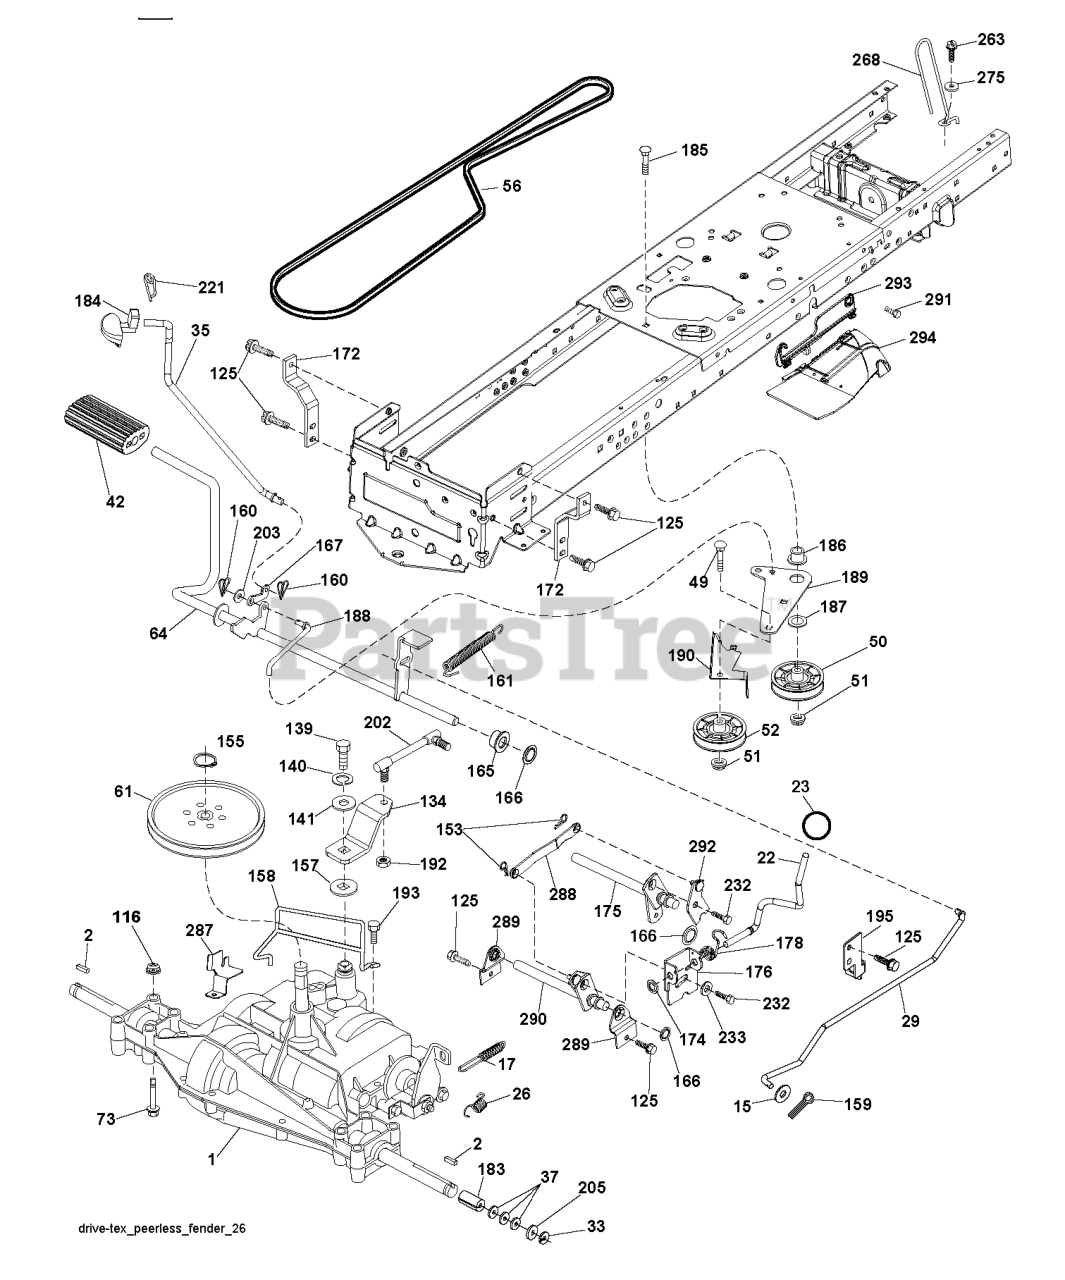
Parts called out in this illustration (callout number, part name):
2	SQUARE KEY
15	WASHER
17	SPRING.BRAKE.PEERLESS.TEX
22	SHIFTER.ASM.HANDLE.SRD
23	KNOB.DUCKHEAD.1/2
26	SPRING.BRAKE.RTN.GR.DR
29	ROD.BRAKE.PEERLESS
35	ROD.CNTRL.PARK.PREDATOR.LT.TEX
42	PEDAL COVER T
50	IDLER.FLAT.910.OFFSET
51	NUT LOCK FLG 3/8-16 UNC
52	IDLER.V-GROOVE.910.OFFSET
56	BELT, V GROUND DRIVE 95 25
61	PULLEY
64	SHAFT.ASM.PEDAL.BRAKE.
73	BOLT HEX 5/16-18 GR 5
116	NUT LOCK HEX FLANGE 5/16-18
125	SCREW
139	BOLT 1/4-28X3/4
140	LOCKWASHER
153	RETAINER M
155	RETAINING RING LT
157	WASH-SHFT PLT LT
158	KEEPER.PMS.18/20.D4365
159	COTTER PIN
160	RETAINER CLIP
161	SPRING, RETURN LT
165	BUSHING.SHAFT.BRAKE.HAND
166	NUT.PUSH.625.2006
167	LATCH.BRAKE.SPRING
172	STRAP.TRQ.LH.GEAR.DRIV
174	NUT.PUSH.500.2006
175	SHAFT ASM SHIFT
176	ARM.CLEVIS.ROD.SHIFT
178	SPRING.TORSION.LIFT.HANDLE
183	SPACER AXLE
184	HANDLE PARKING BRAKE
186	SPACER.RETAINER
187	WASHER 12/32X2X10GA
188	RP.LINK.CLUTCH.GROUND.DRIVE
189	BELLCRANK.GROUND.DRIVE.TEX.
190	KEEPER.BELLCRANK.DRIVE
192	NUT LOCK CENTER 1/4 -28 FNTHD
193	SCREW 5/16"
195	BRKT.ROD.BRAKE.PEERLES
202	LINK.SHIFT.PMST.18" (SPG1286)
203	WASHER
221	RETAINER.SPRING.CLIP.H
232	BOLT FIN HEX 7/16-14 X 1
233	WASHER SERRATED
263	SCREW, 3/8-16X3/4
268	WASHER
275	GUARD MUFFLER
287	KEEPER.PULLEY.T/A.7.04
288	LINK.SHIFT.SLAVE.SRD
289	BRACKET.SUPPORT.SHIFT.OUTER
290	SHAFT.ASM.SHIFT.REAR.SRD
291	SHOULDER BOLT 5/16-18TT
292	PLATE.ASM.SHIFT.FWD.SRD
293	HINGE RIGHT
